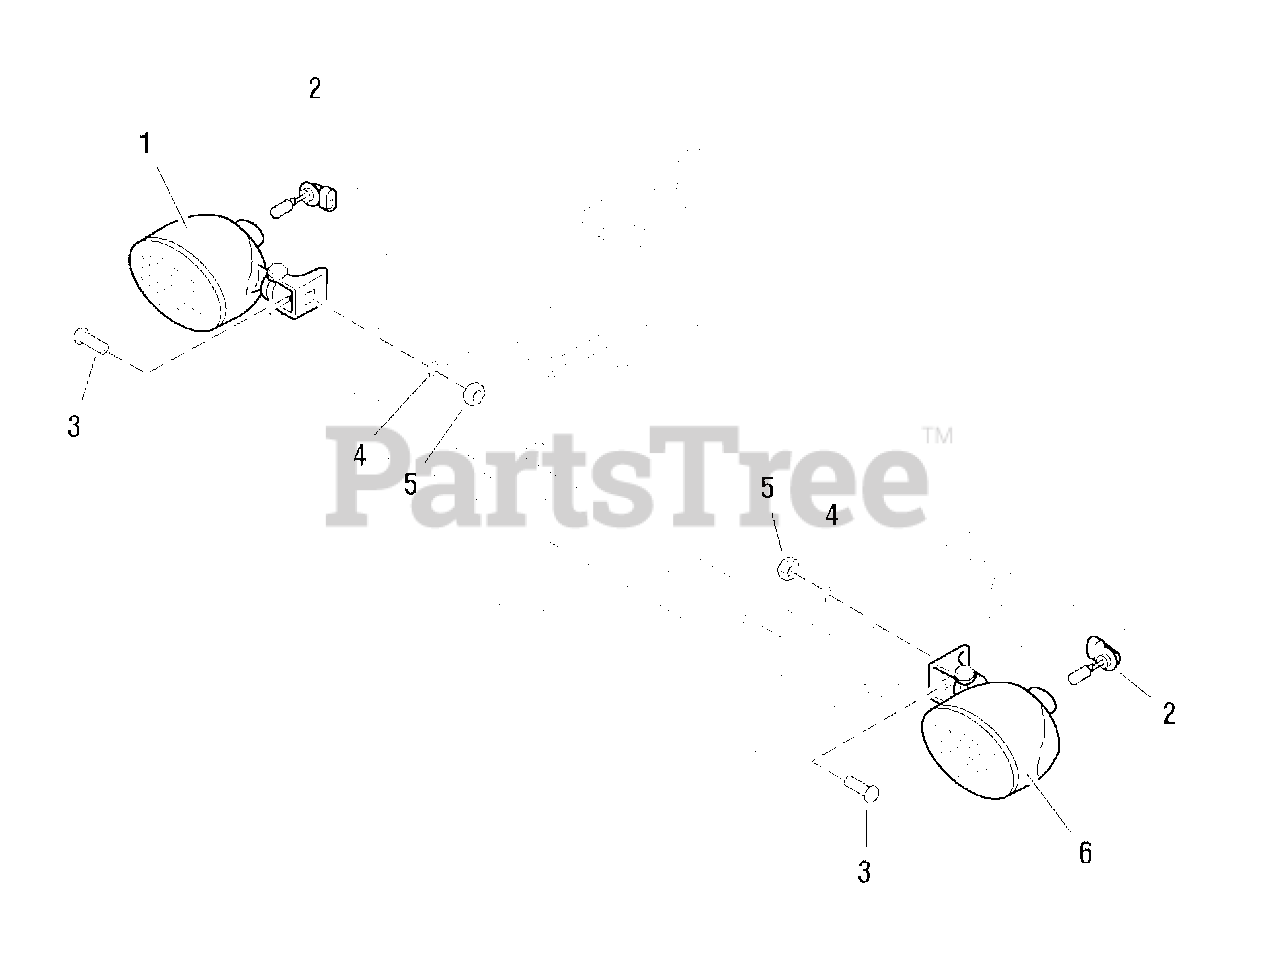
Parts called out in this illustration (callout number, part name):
1	HEADLIGHT-RH, Complete
2	BULB, Headlight
3	CARRIAGE BOLT, 5/16-18 x 1
4	WASHER, Lock, 5/16
5	NUT, Hex, 5/16-18
6	HEADLIGHT-LH, Complete
